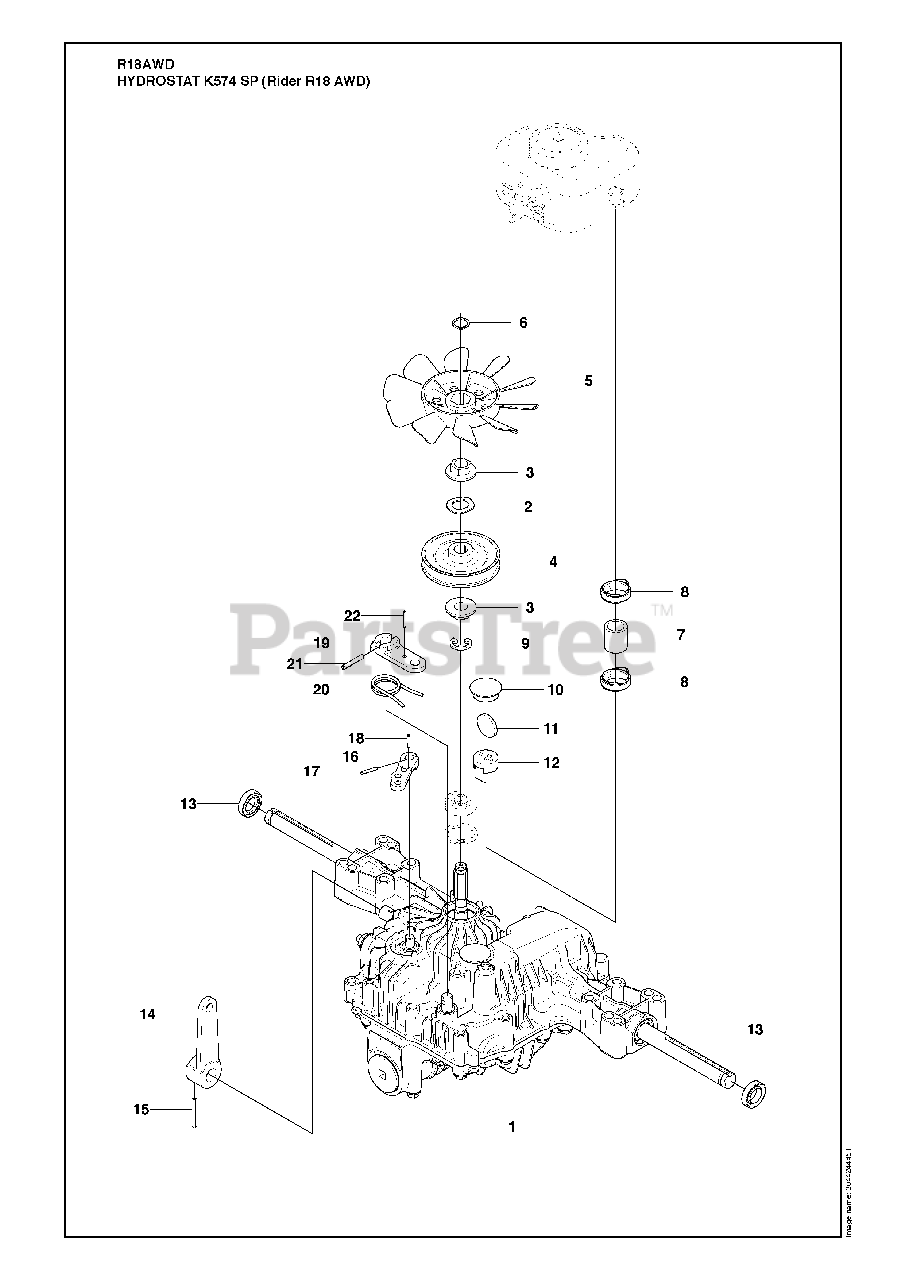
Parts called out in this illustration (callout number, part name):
1	HYDRAULMOTOR
5	FAN.BLACK.1A646083070
6	RETAINING RING **
8	CLAMP
12	MAGNET HOLDER
13	RP SEAL.19, 19216334280
14	CONTROL LEVER
20	RETURN SPRING
